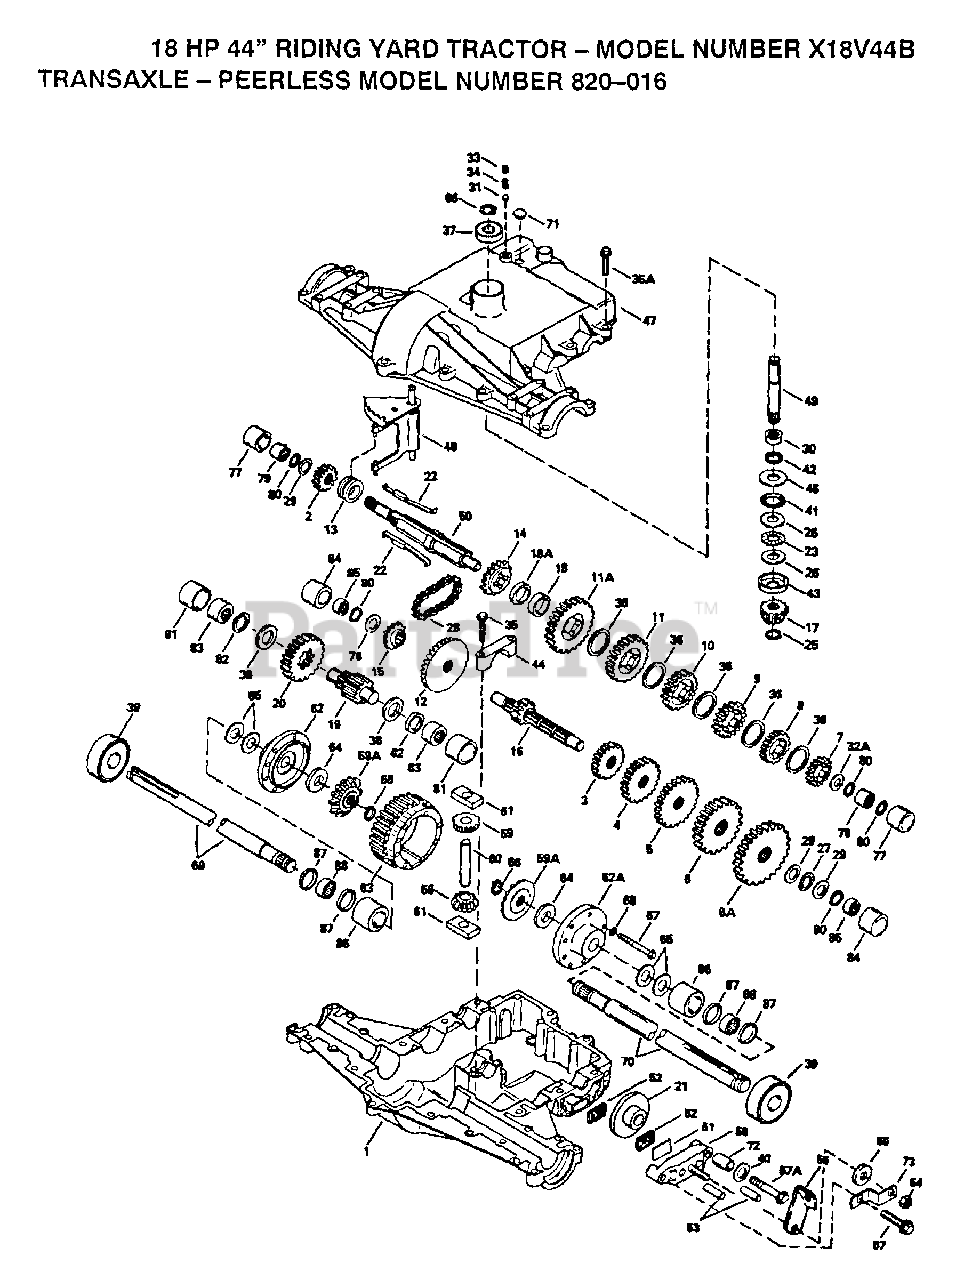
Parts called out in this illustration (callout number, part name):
1	CASE TRANSAXLE
2	GEAR, SPUR, 15T
3	GEAR, SPUR, 12 TEETH
4	GEAR, SPUR, 18 TEETH
5	GEAR, SPUR, 25T
6	GEAR, SPUR, 28T
6A	GEAR, SPUR, 31T
7	GEAR, SPUR, 19 TEETH
8	GEAR, SPUR, 22T
9	GEAR, SPUR, 25T
10	GEAR, SPUR, 32 TEETH
11	GEAR, SPUR, 37 TEETH
11A	GEAR, SPUR, 41T
12	GEAR BEVEL, 33T
13	COLLAR SHIFT
14	SPROCKET 18T (REV)
15	SPROCKET 9T
16	SHAFT COUNTER
17	BEVEL PINION, 13T
18	SPACER, .350/.340 THICK
18A	SPACER, .276/.268 THICK
19	SHAFT, OUTPUT, 9T
20	GEAR, OUTPUT, 35T
23	BEARING THRUST
25	RETAINING RING
26	WASHER THRUST
27	THRUST BEARING
28	CHAIN, ROLLER
29	WASHER THRUST
30	BEARING NEEDLE
31	BALL STEEL, 5/16" DIA.
33	SCREW, 3/8-16 X 3/8"
35	SCREW, 1/4-20 X 1-1/4
35A	SCREW HEX HD 5/16-18 X 1-1/4
36	WASHER THRUST
37	BEARING BALL
38	WASHER THRUST
39	BEARING BALL
40	WASHER FLAT
42	OIL SEAL 3/4
43	WASHER CUPPED
44	BEARING CAP
47	COVER, TRANSAXLE
48	ROD AND FORK ASSY SHIFT
49	SHAFT INPUT
50	SHAFT BRAKE
51	PLATE BRAKE PAD
54	LOCKNUT 5/16-24
55	WASHER, FLAT
56	LEVER BRAKE
57	SCREW, 1/4-20 X 1-1/4
57A	SCREW FLNG HEX 1/4-20 X 2-1/4
58	HOLDER BRAKE PAD
59	PINION, 10T
61	BLOCK DRIVE
62	CARRIER DIFF THREADED HOLES
62A	CARRIER DIFF
63	GEAR, RING, 31T
65	WASHER THRUST
67	SCREW, 1/4-20 X 2-1/4
68	WASHER LOCK 1/4
69	AXLE, 12-5/16" LONG
70	AXLE, 16-3/16" LONG
71	PLUG, THRDED, 9/16-18
73	BRKT BRAKE LEVER
78	BEARING NEEDLE
79	BEARING NEEDLE
81	SLEEVE STEPPED
82	RING SQ CUT
83	BEARING, NEEDLE
84	SLEEVE STEPPED
85	BEARING NEEDLE CAPPED
86	SLEEVE STEPPED
87	RING SQ CUT
88	BEARING NEEDLE
